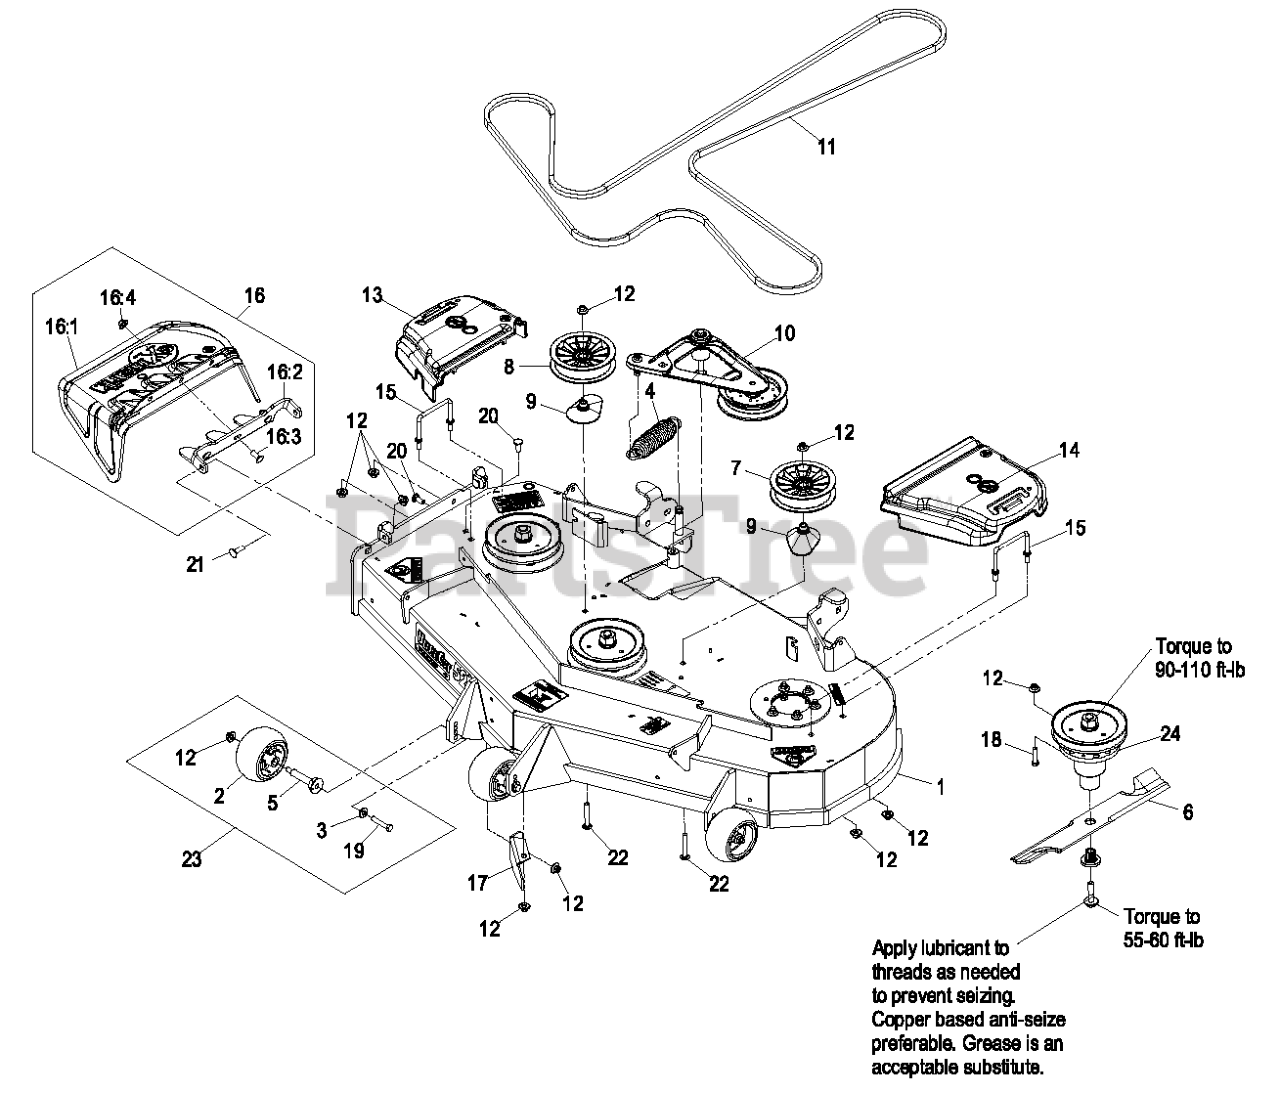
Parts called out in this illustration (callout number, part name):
1	ASM,DECK W/ DECALS 524
2	ROLLER-SCALP, ANTI
3	WASHER-BELLEVILLE
7	PULLEY,IDLER 5"
8	PULLEY,IDLER 6"
9	SPACER-PULLEY
11	BELT,V-B X 186.00"
12	Nut-Nyloc 3/8-16 Flg
13	COVER-BELT, RH
14	COVER-BELT, LH
15	WIREFORM-COVER
16	ASM,DISCHARGE CHUTE
16:1	CHUTE,DISCHARGE
16:2	BRACKET,DISCHARGE CHUTE
16:3	SCREW-CARR
16:4	Nut-Nyloc 3/8-16 Flg
17	BAFFLE,DISCHARGE 52/60
18	SCREW-HH
19	SCREW-HH
20	SCREW-CARR
21	Bolt-Carriage 3/8-16 X 1 1/4
22	SCREW-CARR
24	ASM, CUTTER HOUSING 52
25	Asm, Deck Complete 524
